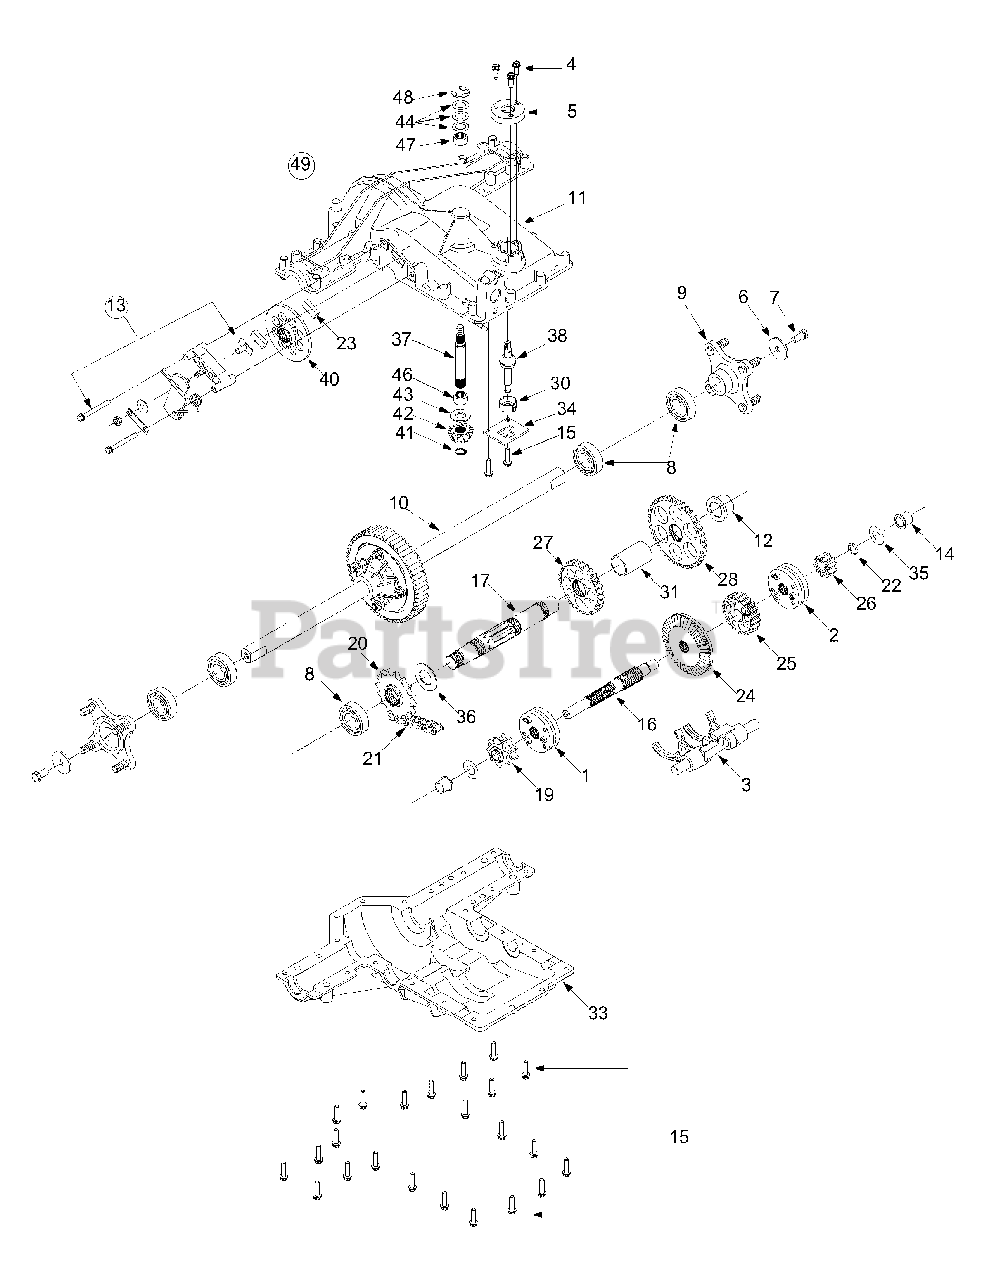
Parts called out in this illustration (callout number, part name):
1	Reverse Collar Assembly
2	Hi-Lo Collar Assembly
3	Shift Fork Assembly
4	Self-tapping Screw, 1/4-20 x .75
5	Shft. Cover
6	Flat Washer
7	Lock bolt 3/8-16 x 0.75
8	Ball Bearing
9	Wheel Hub Assembly
10	Differential Axle Assembly
11	Upper Housing
12	Flanged Bearing
13	Brake Assembly
14	Flanged Bearing
15	TT Screw 1/4-20 x 1.0
16	Drive Shaft
17	Output Shaft
19	9-tooth Sprocket
20	16-tooth Sprocket
21	22-link Chain, .625
22	External Snap Ring
23	Brake Pad
24	41-tooth Bevel Gear
25	20-tooth Spur Gear
26	10-tooth Spur Gear
27	27-tooth Spur Gear
28	37-tooth Spur Gear
30	Shifter Insert
31	Shifter Cover
33	Lower Housing
34	Lockout Plate
35	Flat Washer, 5/8 x 1.0
36	Flat Washer, 1.01 x 1.86 x .060
37	Input Shaft
38	Shift Lever
40	Disc Brake
41	Retaining Ring, .56
42	13-tooth Bevel Gear
43	Flat Washer
44	Flat Washer, 5/8 x 1.0 x .030 (as required)
44	Flat Washer, 5/8 x 1.0 x ..040 (as required)
44	Falt Washer,5/8 x 1.0 x .020 (as required)
46	Needle Bearing
47	Needle Bearing
48	E-ring, .75
49	Transmisssion Assembly Complete
